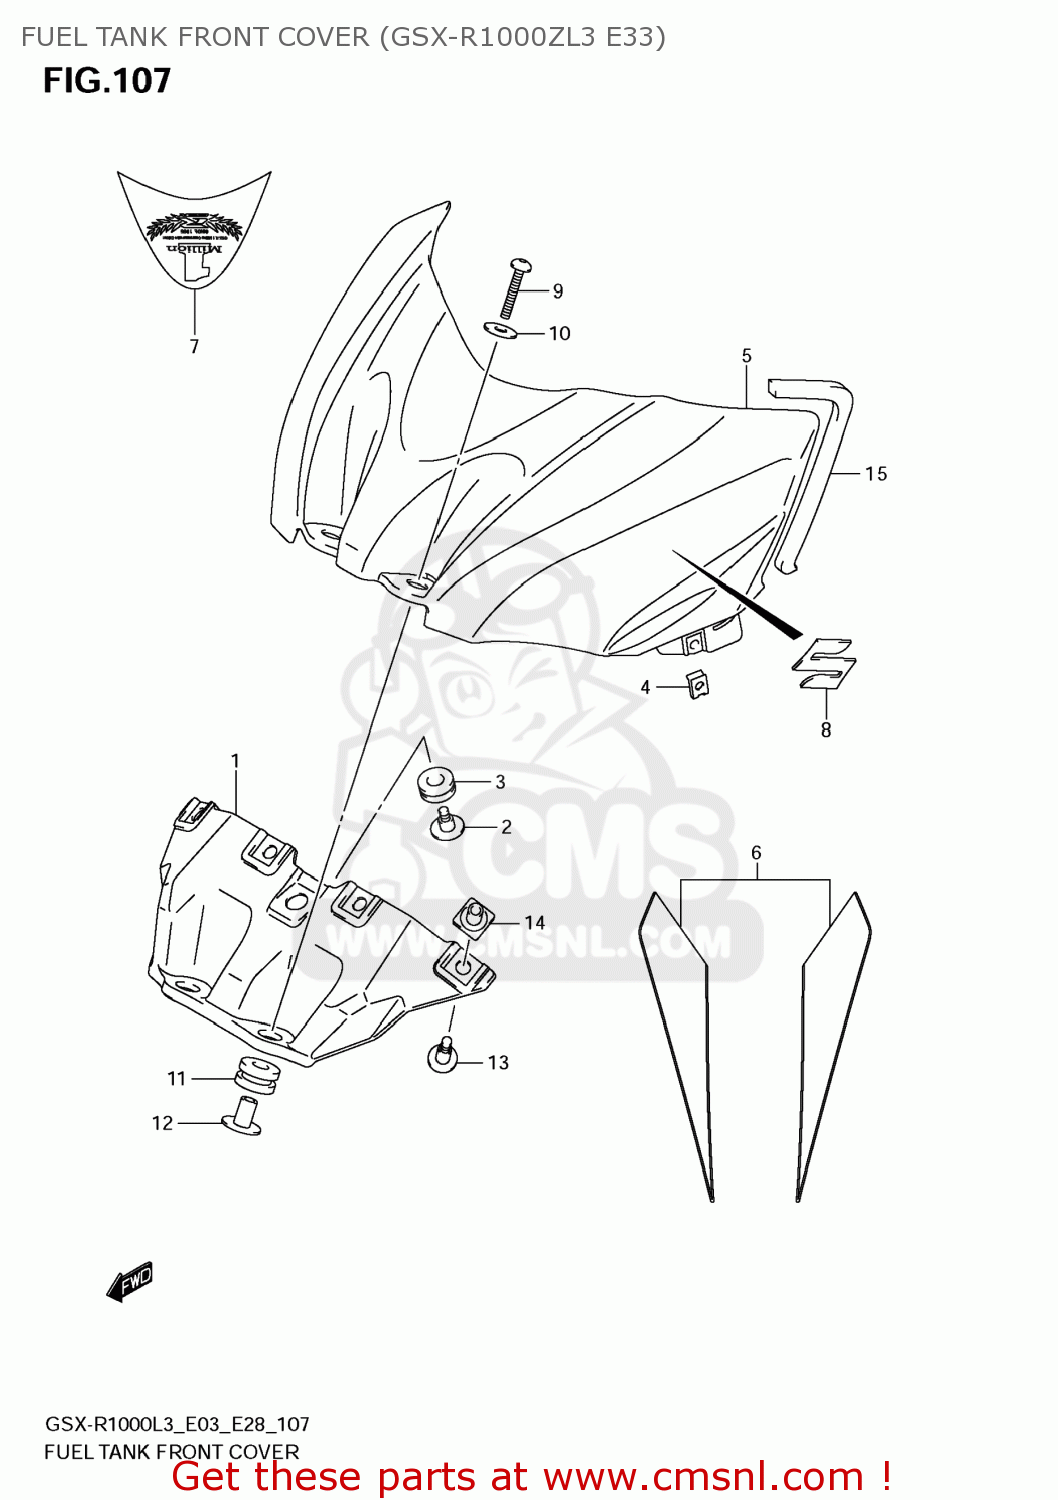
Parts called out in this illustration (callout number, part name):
1	BRACKET,FUEL TANK FR
2	SCREW(5X16.4)
3	CUSHION
4	NUT
5	COVER,FUEL TANK FR
6	TAPE SET,FUEL TANK COVER
7	TAPE,FUEL TANK COVER CTR
8	EMBLEM,S
9	SCREW(6X40)
10	WASHER(6,5X22X1.6)
11	CUSHION
12	SPACER,FUEL TANK FR
13	SCREW(6X10)
14	NUT(M6)
15	CUSHION,FUEL TANK COVER
